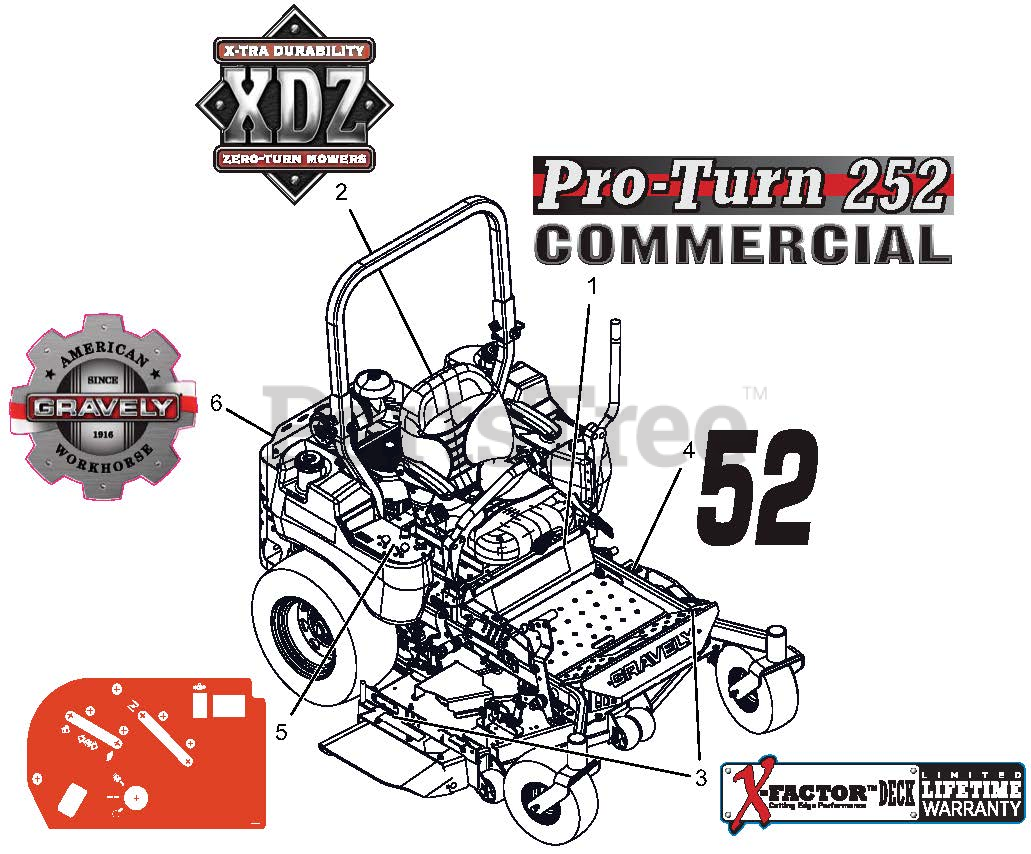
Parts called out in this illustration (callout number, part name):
1	DECAL, PROTURN 252
2	DECAL, XDZ
3	DECAL, X-FACTOR DECK
4	DECAL, 52"
5	DECAL, CONTROL PANEL NON-EFI
6	DECAL, GRAVELY HERITAGE-LARGE
